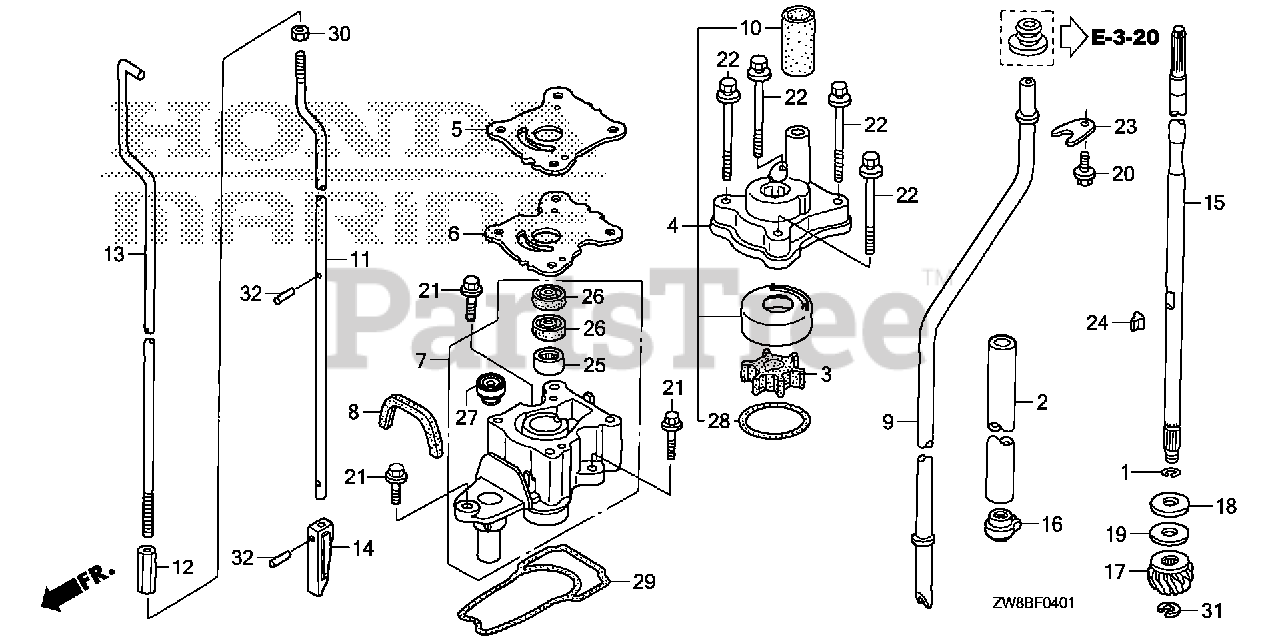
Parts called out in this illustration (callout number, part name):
1	CLIP, VALVE GUIDE
2	GUIDE, OIL (UL)
3	IMPELLER, PUMP (UL)
4	HOUSING ASSY., IMPELLER
5	COVER, IMPELLER
6	GASKET, IMPELLER
7	HOUSING, WATER PUMP (UL)
8	GROMMET, WATER PUMP HOUSING
9	TUBE, WATER (UL)
10	RING, WATER TUBE SEAL
11	ROD B, SHIFT (UL)
12	JOINT, SHIFT ROD
13	ROD A, SHIFT (L)
14	ROD, PUSH
15	SHAFT, VERTICAL (UL)
16	SLINGER, OIL (UL)
17	GEAR, PINION
18	WASHER A, THRUST BEARING
19	WASHER B, THRUST BEARING
19	WASHER C, THRUST BEARING
20	BOLT, FLANGE (6X12)
21	BOLT, FLANGE (6X20)
22	BOLT-WASHER (6X90)
23	PLATE, WATER TUBE SETTING
24	KEY, WOODRUFF
25	BEARING, NEEDLE (15X21X12)
26	SEAL, WATER (15X24X5)
27	SEAL, WATER (6MM)
28	O-RING (42.2X2.4)
29	O-RING, WATER PUMP HOUSING
30	NUT, HEX. (6MM)
31	E-RING (8MM)
32	ROLLER (2.5X11.8)
